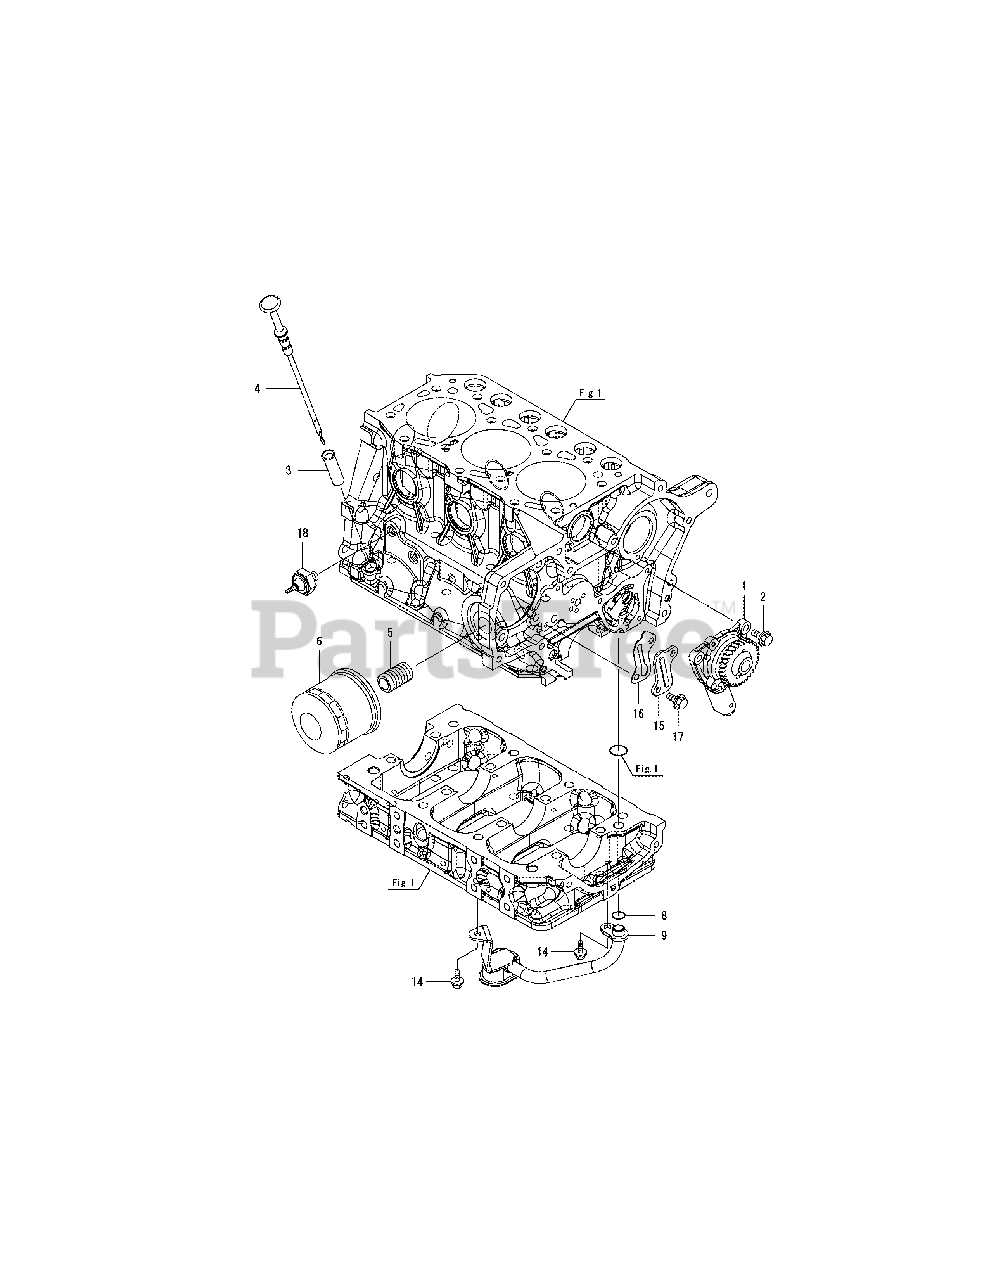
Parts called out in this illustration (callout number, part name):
1	PUMP ASSY, LUB.OIL
2	BOLT M 6X 14 PLATED
3	GUIDE, DIPSTICK
4	DIPSTICK, ASSY
6	FILTER ASSY, LUB.OIL
9	PIPE ASSY, LUB,OIL
14	BOLT 6X 10 PLATED
17	BOLT 6X 10 PLATED
18	SWITCH, OIL PRESSURE
